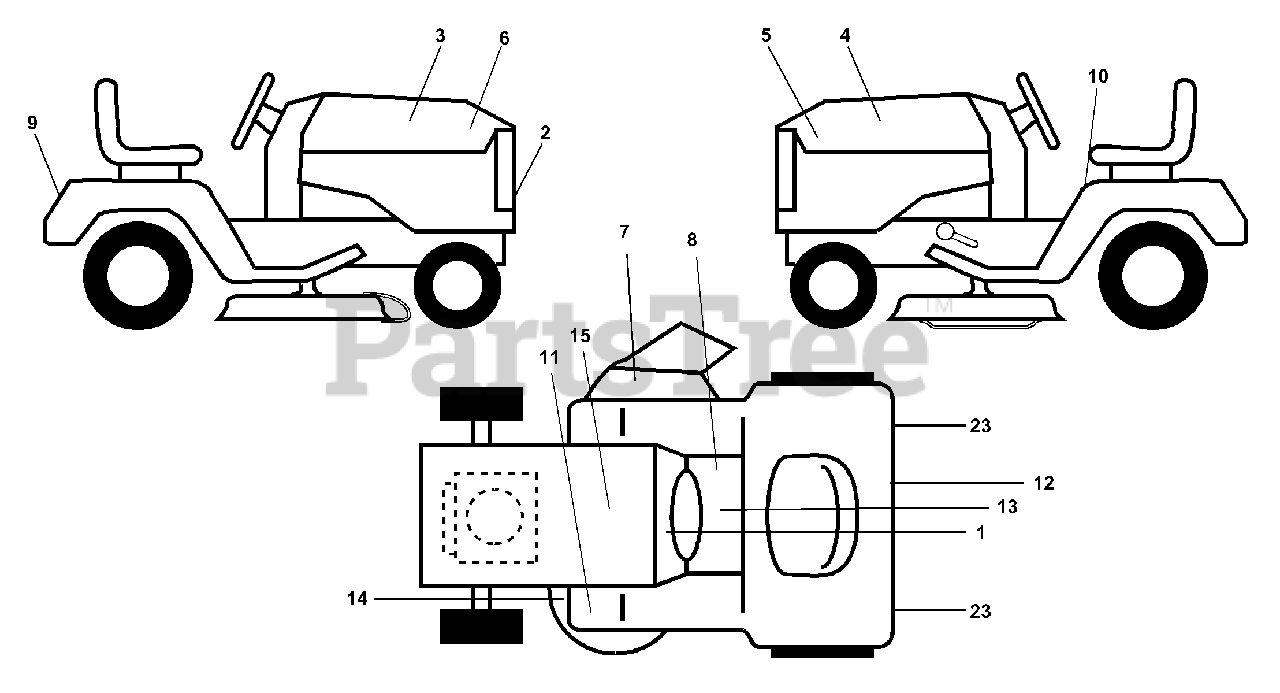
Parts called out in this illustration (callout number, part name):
1	Decal, Operating Instruction
2	Decal, Grille Husqvarna "H" Logo
3	Decal, Hood, RH
4	Decal, Hood, LH
5	Decal, Inst Hood LH GTH200 Hydro
6	Decal, Insrt Hood RH GTH200 Hydro
7	Decal, Warning Multi-Language
8	Decal, Brake Parking Saddle
9	Decal, Fender
10	Decal, Caution
11	Decal, Clutch/Brake
12	Decal, D-Bar Ctrl. Mvt Hyd YT/GT
13	Decal, Cold Start
14	Decal, V-Belt Schematic
15	Decal Bat Dan/Poi P/L Symbols
23	Reflector, Taillight
